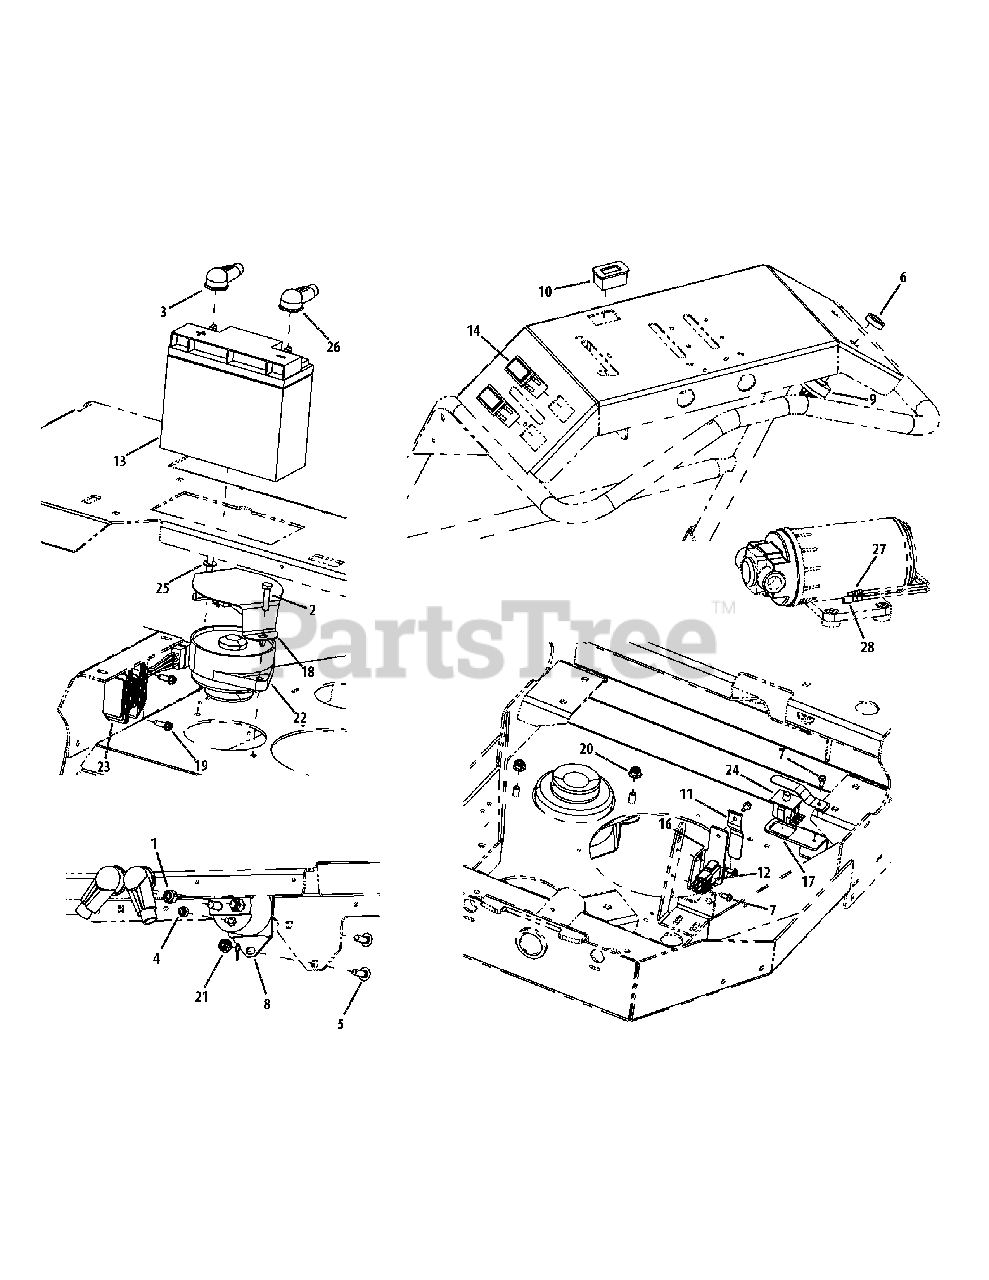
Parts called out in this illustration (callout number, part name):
1	Nut, 5/16-18
2	HHCS, 5/16-18 x 1-1/4
3	Boot, 1" OD Rubber Battery-PST, Red
4	Nut, Lock, Nylon Insert, #10-32
5	Carriage Bolt, 1/4-20 x .75
6	Nut, W/Cap, 5/8-32 Ignition
7	Self Tapping Screw, #10-24 x 0.500
8	Solenoid Magnetic Switch
9	Switch, Ignition, 6 Pin includes:
10	Hour Meter w/ Clip
11	Retainer Spring
12	Delta Switch, NO/NC
13	Battery, 12v
16	Bracket, Neutral
17	Bracket, Park Brake
18	Alternator Cover
19	Self Tapping Screw, 1/4-20 x .75
20	Nut, 5/16-18, Nylon Flange Lock
21	Nut, 1/4-20, Nylon Flange Lock
22	Alternator, 12V-20A
23	Regulator, Electric, 20A
25	Washer, .344 x .688 x .065
25	Washer, Flat
26	Boot, Rubber Battery, Black
27	Male Connector
28	Female Connector
